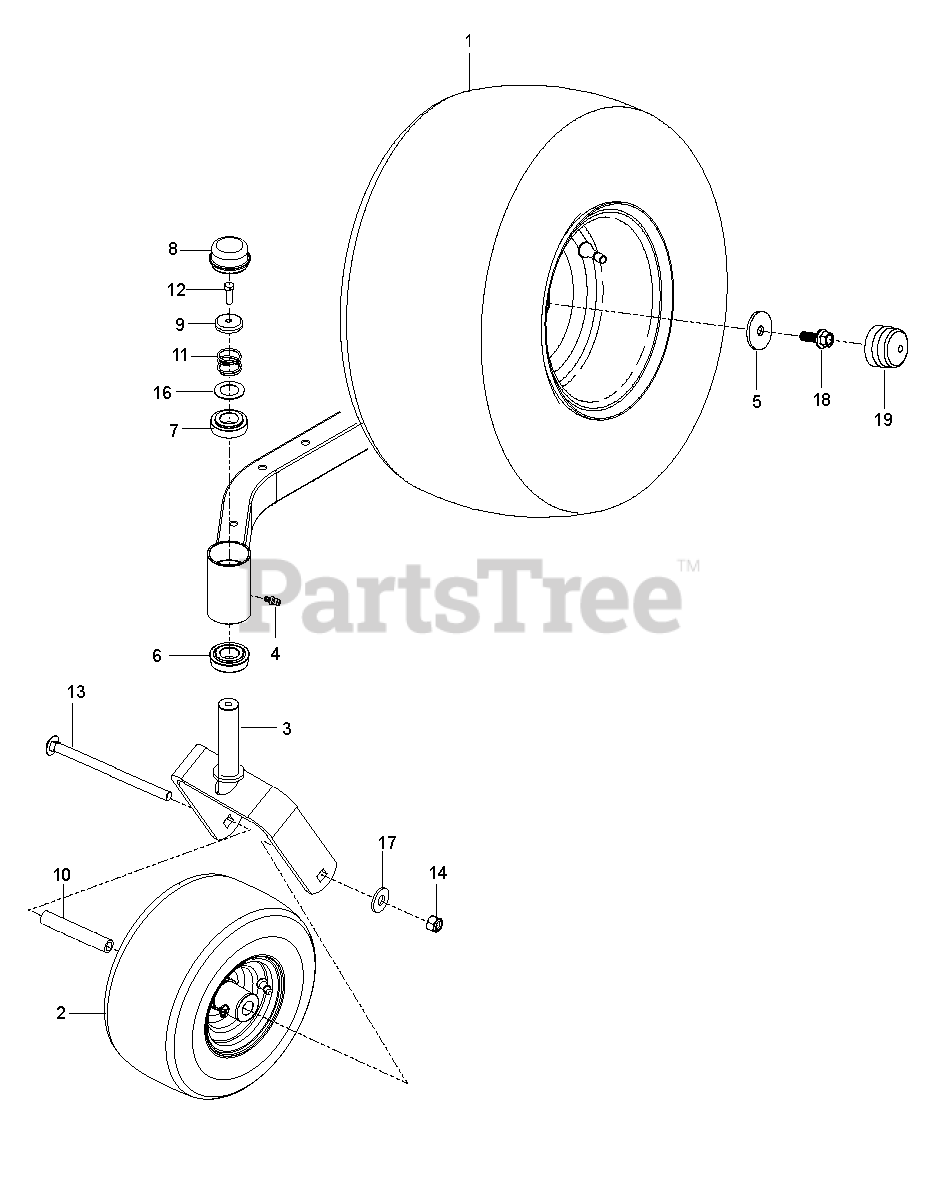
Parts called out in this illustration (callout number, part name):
1	WHEEL (REAR)
2	WHEEL.CARLSTAR.11X4-5".MS417
3	YOKE.CASTER.ORANGE
4	ZERK, 3/16, DRIVE IN
5	WASHER ROUND 3/8 X 1-5/8 X.125
6	BEARING FLANGED
7	BUSHING, CASTER
8	GREASE CAP
9	CASTER.PLUG
10	SPACER
10	SPACER.PIVOT.CONTROL
11	SPRING, CASTER
12	5/16-18X1 HHB G5W/NY
13	RHSNB 1/2-13 X 6.50 GR5 ZD
14	NUT. 1/2-13 HEX CNTRLK GR 5 ZD
16	WASHER, 1.025 ID X 1.64
17	WASHER.9/16 X 1 3/8 X 12 GA.
18	HHFS 3/8-16 X 1 GRD 5 ZD
19	CAP, AXLE BLK
